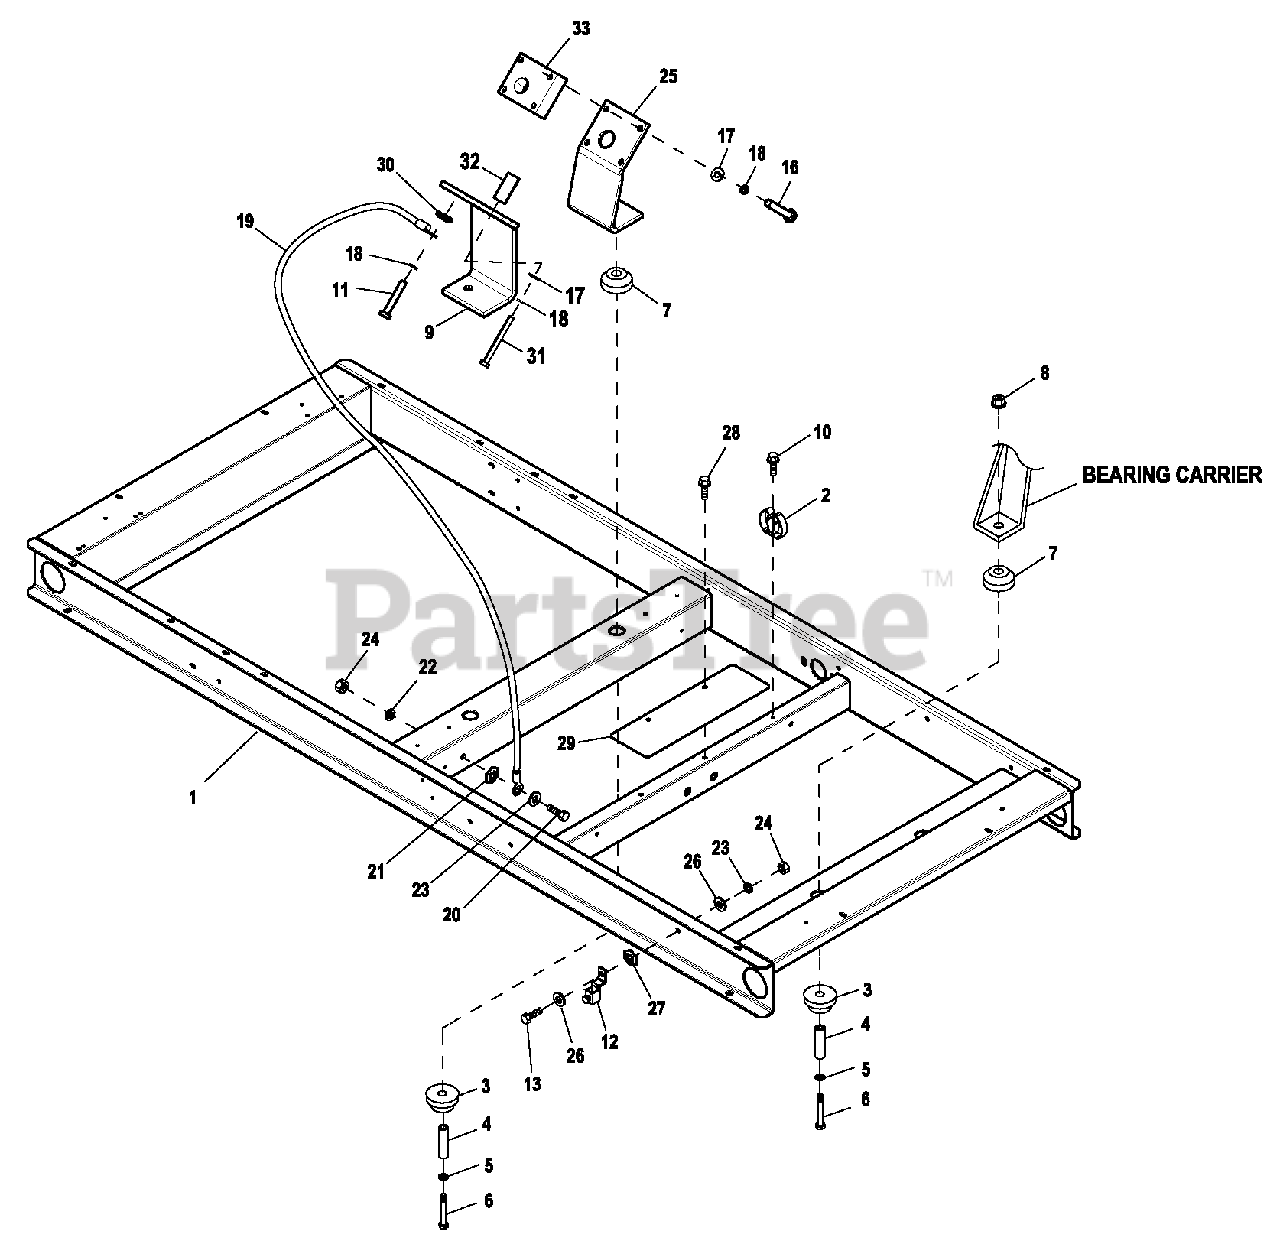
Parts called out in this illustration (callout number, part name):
1	WELDMENT BASEFRAME 5.4L G3
2	SPRING CLIP HOLDER .37- 62
3	DAMPENER VIBRATION
4	SPACER .49 X .62 X 1.87 PWDR/ZINC
5	WASHER FLAT M12
6	SCREW HHC M12-1.75X85 G8.8
7	DAMPENER VIBRATION 50 WHITE
8	NUT LOCKING M12-1.75
9	ENGINE MOUNT 5.4LLH SIDE
10	SCREW HHTTM4-0.7X8BP
11	SCREW HHC M10-1.5X70 C8.8
12	LUG SLDLSS #2-#8 X 17/64 CU
13	SCREW HHC M6-1.0 X 16 C8.8
16	SCREW HHC M10-1.5X60 C8.8
17	WASHER FLAT 3/8-M10ZINC
18	WASHER LOCK M10
19	ASSY WIRE 14.00"
20	SCREW HHC M8-1.25X30 G8.8
21	WASHER LOCK SPECIAL 5/16
22	WASHER LOCK M8-5/16
23	WASHER LOCK M6-1/4
24	NUT HEX M8-1.25 G8 YELCHR
25	ENGINE MOUNT 5.4L RH SIDE
26	WASHER FLAT 1/4-M6 ZINC
27	WASHER LOCK SPECIAL 1/4"
28	SCREW HWHT M6-1 X 16 N WA Z/JS
29	BLOCK OFF, ALTERNATOR
30	WASHER LOCK SPECIAL 3/8
31	SCREW HHC M10-1.5X 100 C8.8
32	SPACER .41 X .7 5 X 1 .6 8 ST/ZNC
33	5.4L RH ENGINE MOUNT SPACER
